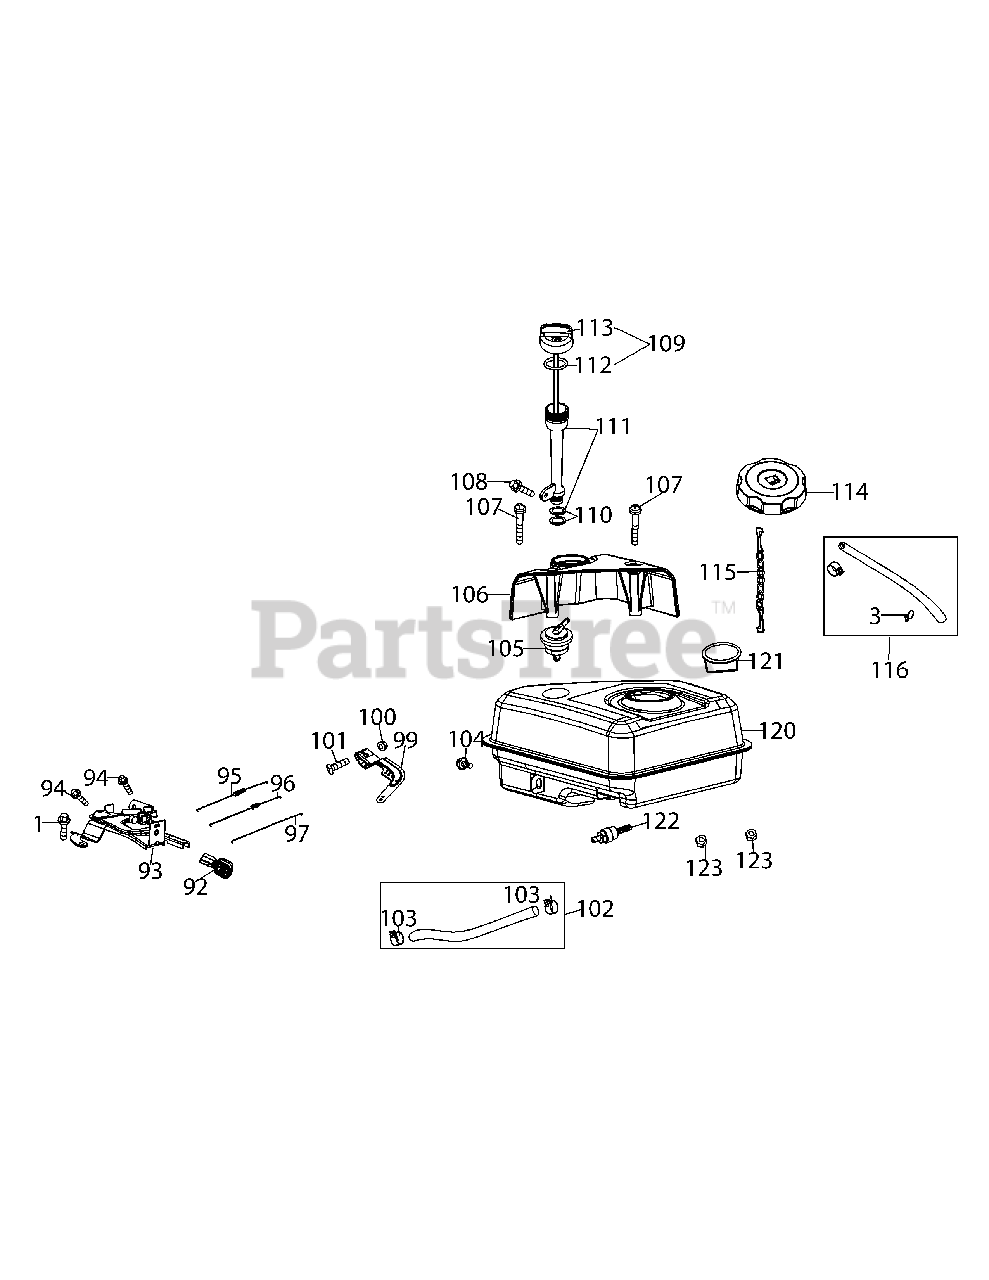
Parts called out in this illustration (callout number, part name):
1	Bolt M6×16
3	Breather Hose Clamp
92	Throttle Control Knob
93	Primer Bracket
94	Bolt M6×12
95	Governor Spring
96	Throttle Linkage Spring
97	Throttle Linkage
99	Governor Arm
100	Nut M6
101	Governor Arm Bolt
102	Fuel Line Kit
103	Fuel Hose Clamp
104	Bolt M6×12
105	Rollover Valve
106	Dipstick Decoration Cover
108	Bolt M6×12
109	Dipstick Assembly
110	Oil Fill Tube O-Ring
111	Oil Fill Tube Assembly
112	Oil Fill Tube O-Ring
113	Dipstick Guage
114	Cap Comp,Fuel
116	Primer Line Kit
120	Fuel Tank Assembly
121	Fuel Level Indicator
122	Fuel Tank Nipple
123	Nut, M6
